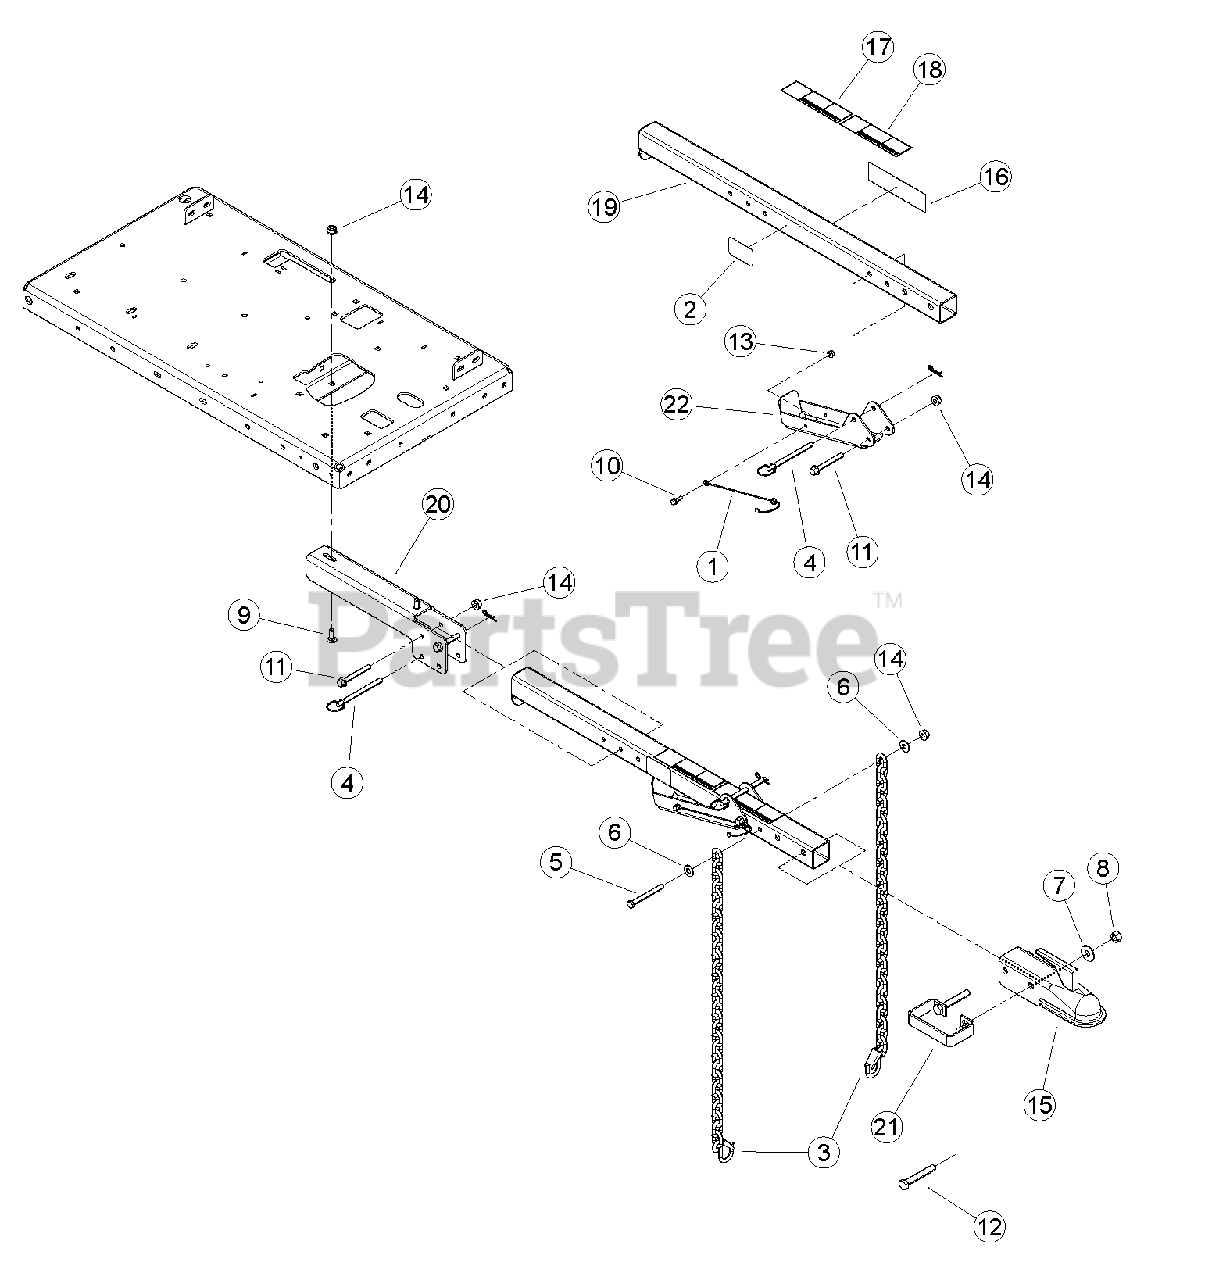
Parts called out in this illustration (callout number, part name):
1	LANYARD, NYLON
2	REFLECTOR, WIDE ANGLE AMBER
3	CHAIN, SAFETY 5000 LB W/ LATCH
4	PIN, 3/8 HITCH
5	BOLT, 3/8 X 3-1/2" HEXHD GR5 ZP
6	WASHER, 3/8" FLAT ZP
7	WASHER, 1/2" FLAT ZP
8	NUT, 1/2" CENTERLOCK GRB ZP
9	BOLT, 3/8 X 1" CRG GR5 NC ZP
10	BOLT, 1/4-20 X 3/4 HWH GR5 CZP
11	BOLT, 3/8 X 3 FLANGE NC
12	BOLT, 1/2 X 3 1/4 HCS GR5 ZP
13	NUT, 1/4-20 NYLOCK-FLANGE
14	NUT, 3/8-16 NYLOCK FLANGE
15	TRAILER HITCH COUPLER
16	DECAL, SAFETY CHAINS
17	DECAL, TRAILER ELECTRICAL
18	DECAL, SAFE COUPLING
19	WELDMENT, HITCH POLE
20	CHANNEL, HITCH POLE
21	HANDLE, COUPLER
22	STAND, JACK
